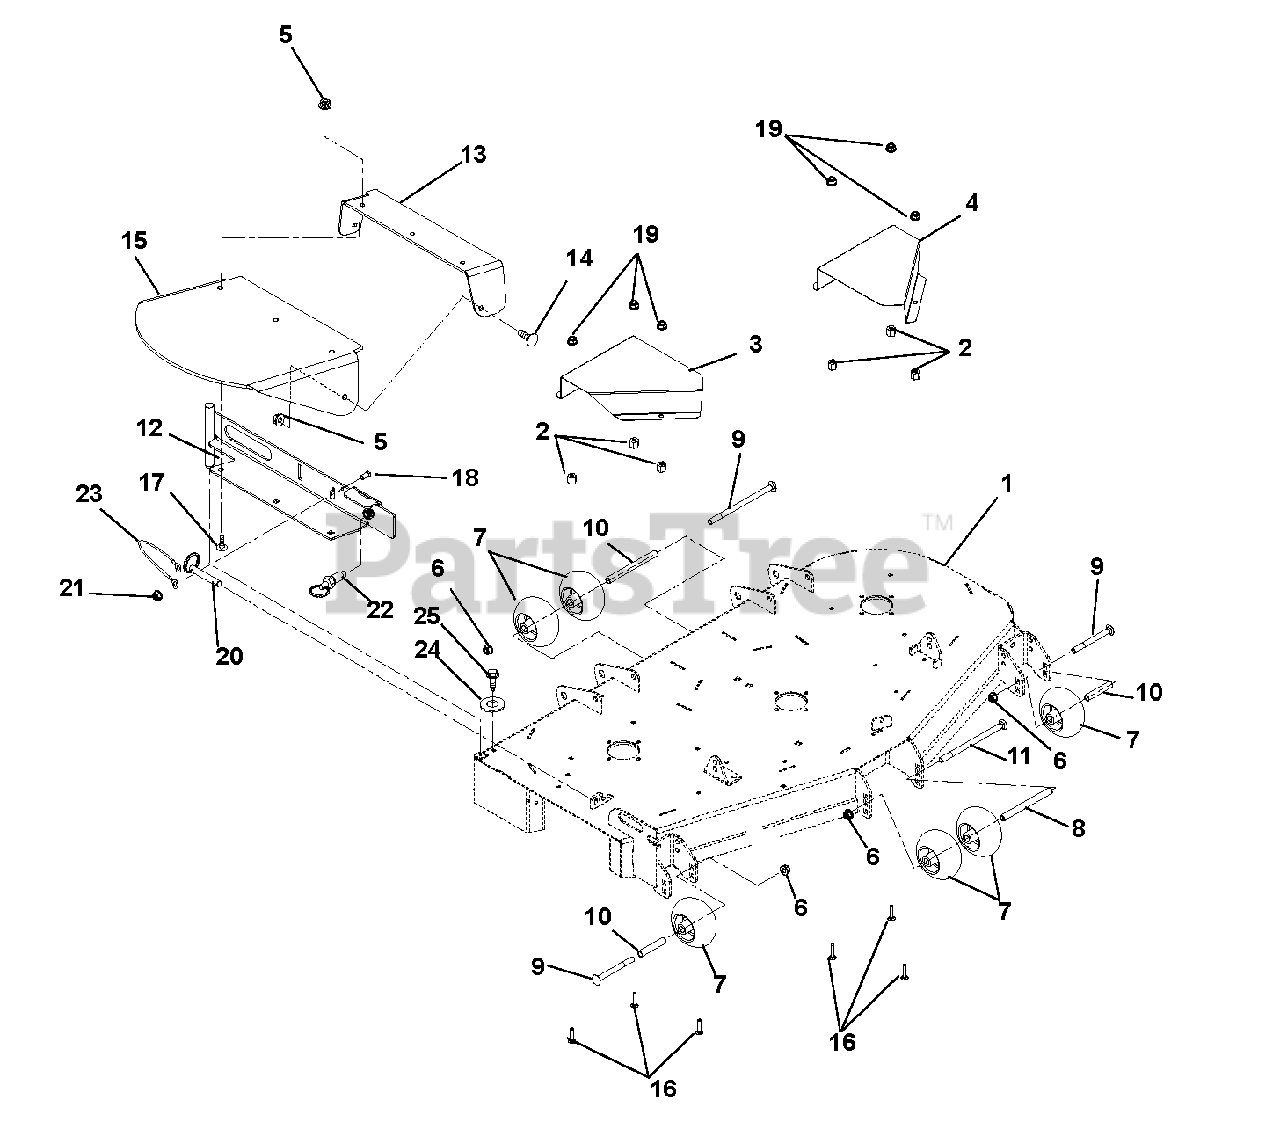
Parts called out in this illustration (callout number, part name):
1	Weldment, 60" Side Discharge Deck (991084)
1	Weldment, 52" Side Discharge Deck (991083)
1	Weldment, 48" Side Discharge Deck (991083)
1	Weldment, 44" Side Discharge Deck (991090)
2	Nut, Heavy Hex .38-16
3	Guard, 60" Spindle Sheave RH (991084)
3	Guard, 48"-52" Spindle Sheave Guard RH (991082, 083, 090)
4	Guard, 60" Spindle Sheave LH (991084)
4	Guard, 52" Spindle Sheave LH (991082, 083, 090)
5	Nut, .38-16 Nyloc Flange
6	Nut .50-13 Nyloc Flange
7	Anti-Scalp Wheel (991082)
7	Anti-Scalp Wheel (991083, 084, 090)
8	Spacer, Anti-Scalp Wheel (991082)
8	Spacer, Anti-Scalp Wheel (991083, 084, 090)
9	Bolt, Round Head Square Neck .50-13 x 5.00 (991082)
9	Bolt, Round Head Square Neck .50-13 x 5.00 (991083, 084, 090)
10	Spacer, .510 x .625 x 3.35 (991082)
10	Spacer, .510 x .625 x 3.35 (991083, 084, 090)
11	Bolt, Round Head Square Neck .50-13 x 8.50 (991082)
11	Bolt, Round Head Square Neck .50-13 x 8.50 (991083, 084, 090)
12	Weldment, 44" & 48" Discharge Chute Mounting (991082, 090)
12	Weldment, 52" – 60" Discharge Chute Mounting (991083, 084)
13	Rubber Discharge Chute Support
14	Bolt, Round Head Square Neck .38-16 x 1.00 Grade 5
15	Chute, Rubber Discharge
16	Bolt, Hex .38-16 x 1.25 Grade 5
17	Bolt, Round Head Square Neck .38-16 x 1.25 Grade 5
18	Bolt, Hex .25-20 x .75 Grade 5
19	Nut, Flange .375-16
20	Pin, Spring Ball .375 OD x 1.50
21	Nut-Locking-Top-Flange .25-20
22	Pull Pin
23	Cable, 6.00 Lanyard - Nylon
24	Bumper, Recessed 1.50 x .63 W/.31 Thru Hole
25	Screw, Tapping .31-18 x .75 Hex Washer Head
